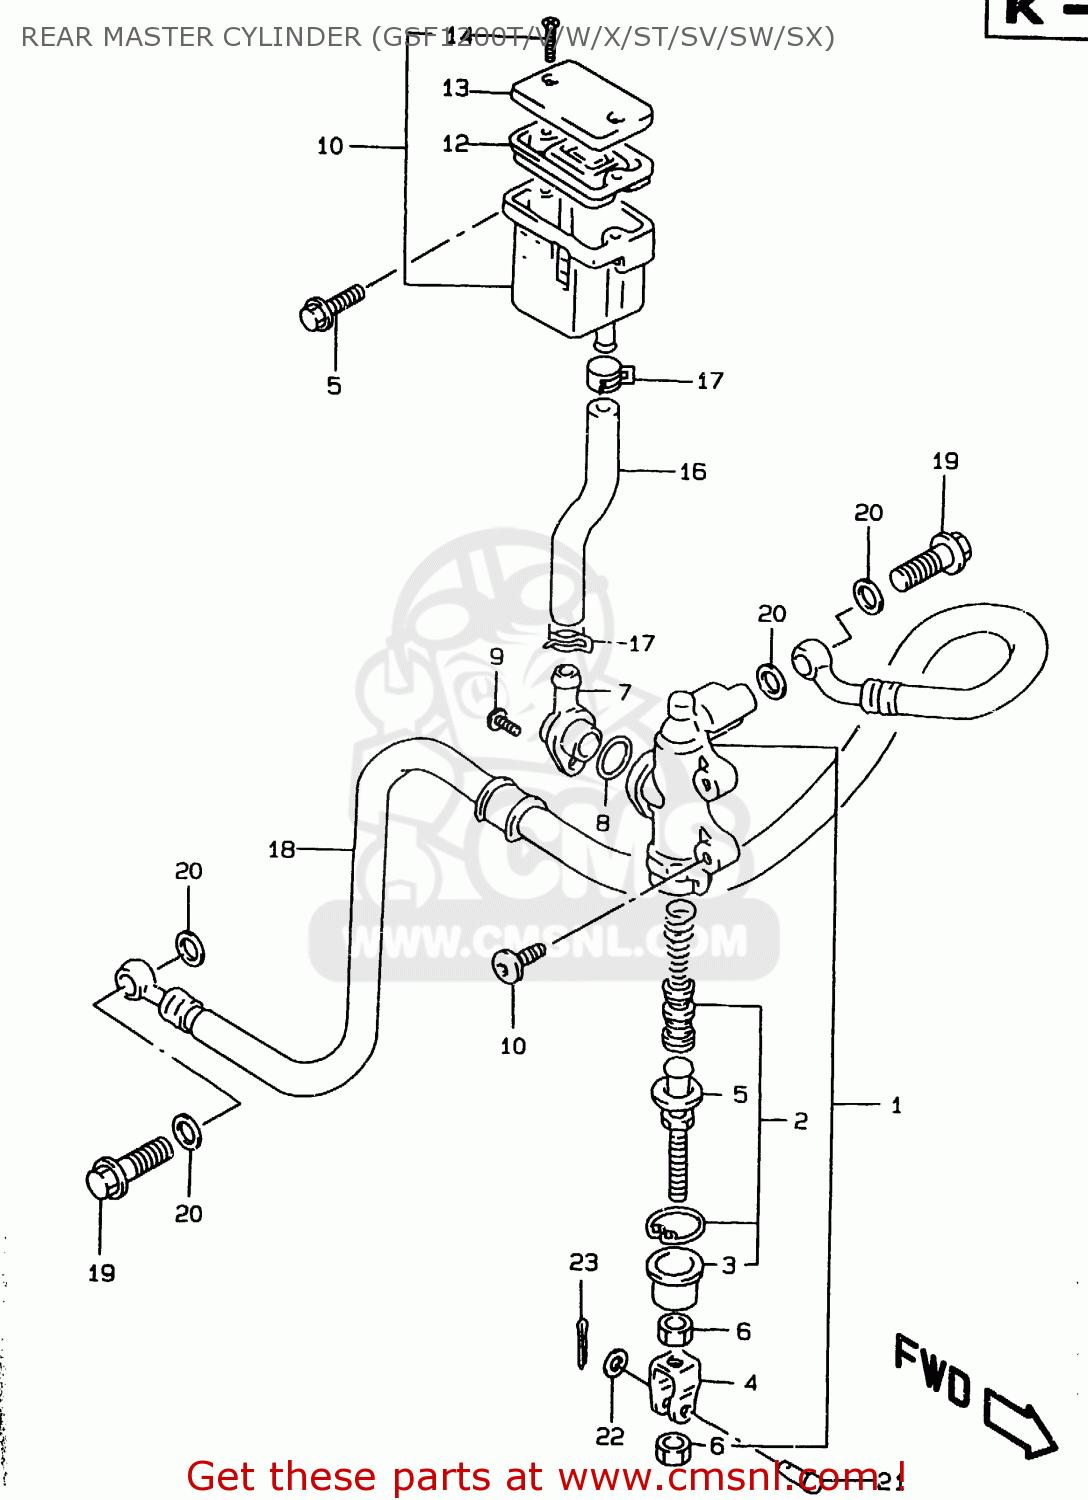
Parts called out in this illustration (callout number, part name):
1	CYLINDER ASSY,RR MASTER
2	PISTON/CUP SET
3	BOOT
4	YOKE
5	ROD,PUSH
6	NUT
7	CONNECTOR
8	O RING
9	SCREW
10	BOLT 8X20
11	TANK ASSY,RESERVOIR
12	DIAPHRAGM
13	CAP
14	SCREW
15	BOLT
16	HOSE,RESERVOIR TANK
17	CLIP
18	HOSE,RR BRAKE
19	BOLT UNION
20	WASHER(10X15X1.5)
21	PIN
22	WASHER
23	PIN
